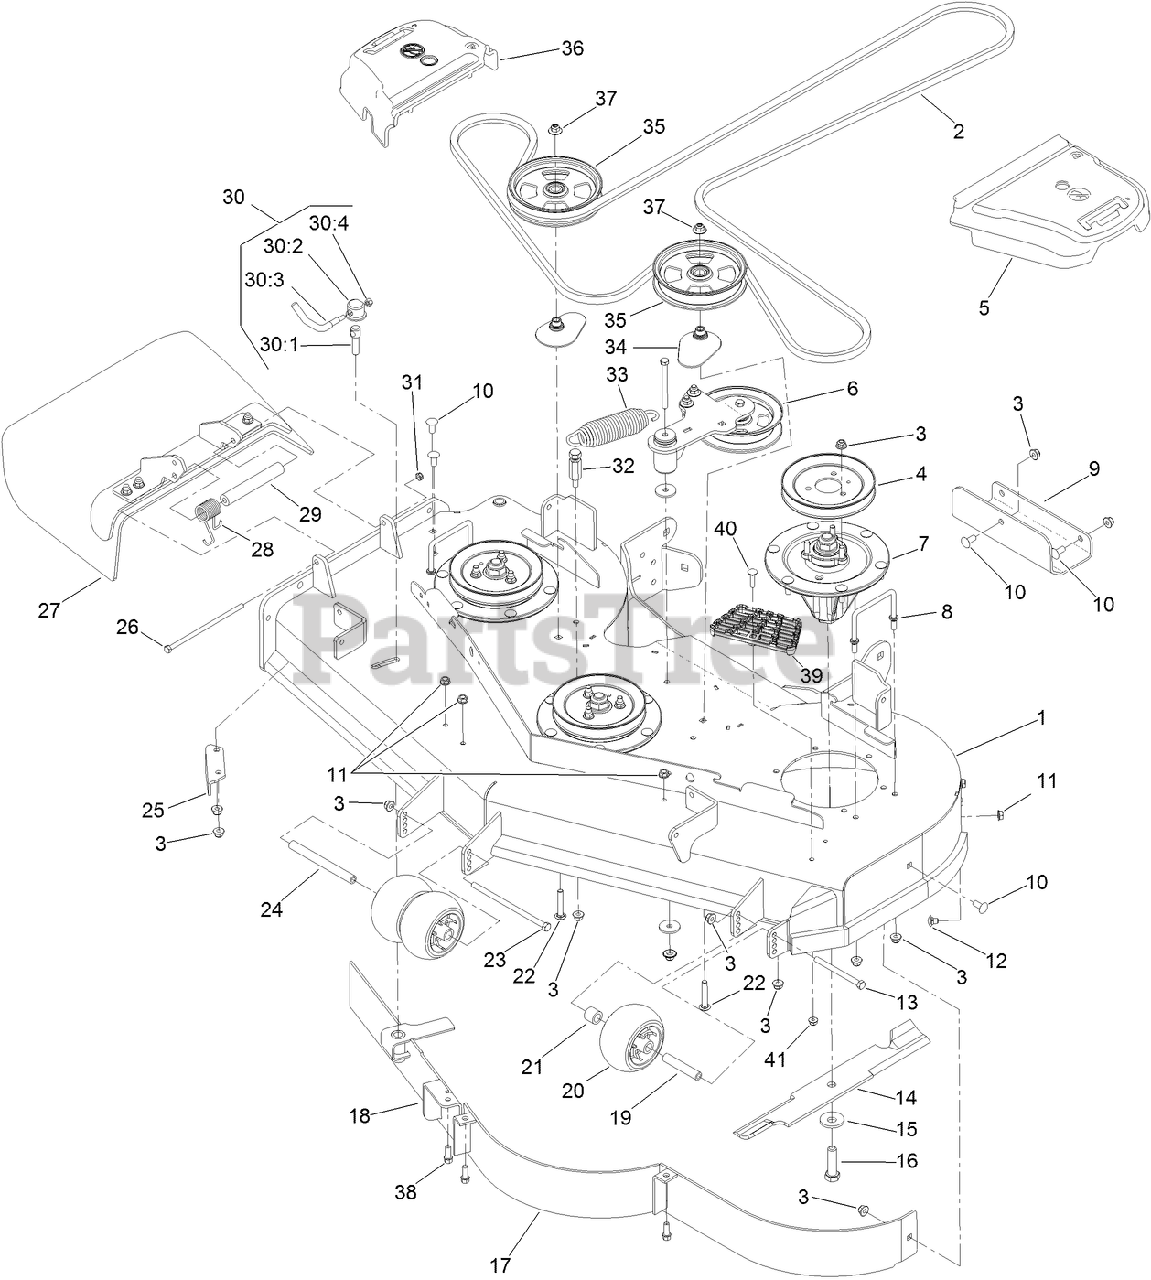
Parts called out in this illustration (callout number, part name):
1	DECK DECAL ASM
2	BELT-V
3	NUT-HF, NI
4	PULLEY
5	COVER-BELT, LH
6	IDLER ARM ASM
7	SPINDLE ASM
8	WIREFORM-COVER
9	PLATE-SKID
10	SCREW-CARR
11	NUT-HHF, WHIZ
12	SCREW-CARR
13	SCREW-HH
14	BLADE-18IN, HI FLOW
15	WASHER-BLADE BOLT, HEAVY
16	SCREW-BLADE
17	BAFFLE ASM
18	ADJUSTABLE BAFFLE ASM
19	TUBE-SPANNER
20	ROLLER-SCALP, ANTI
21	TUBE-SPACER
22	BOLT-CARR, SHORT NECK
23	SCREW-HH
24	SPACER-WHEEL
25	BAFFLE-DISCHARGE
26	SCREW-HH
27	RUBBER DEFLECTOR ASM
28	SPRING-TORSION
29	SPACER
30	LEVER ASM
30:1	SCREW-LOCK
30:2	CAP-LOCK
30:4	NUT-LOCK, NI
31	NUT-LOCK, NI
32	ANCHOR-SPRING, TALL
33	SPRING-EXTENSION
34	SPACER-PULLEY
35	PULLEY-IDLER, FLAT
36	COVER-BELT, RH
37	NUT-FLANGE, NI
39	STEP-DECK
40	SCREW-CARR
41	NUT-HF, NI
